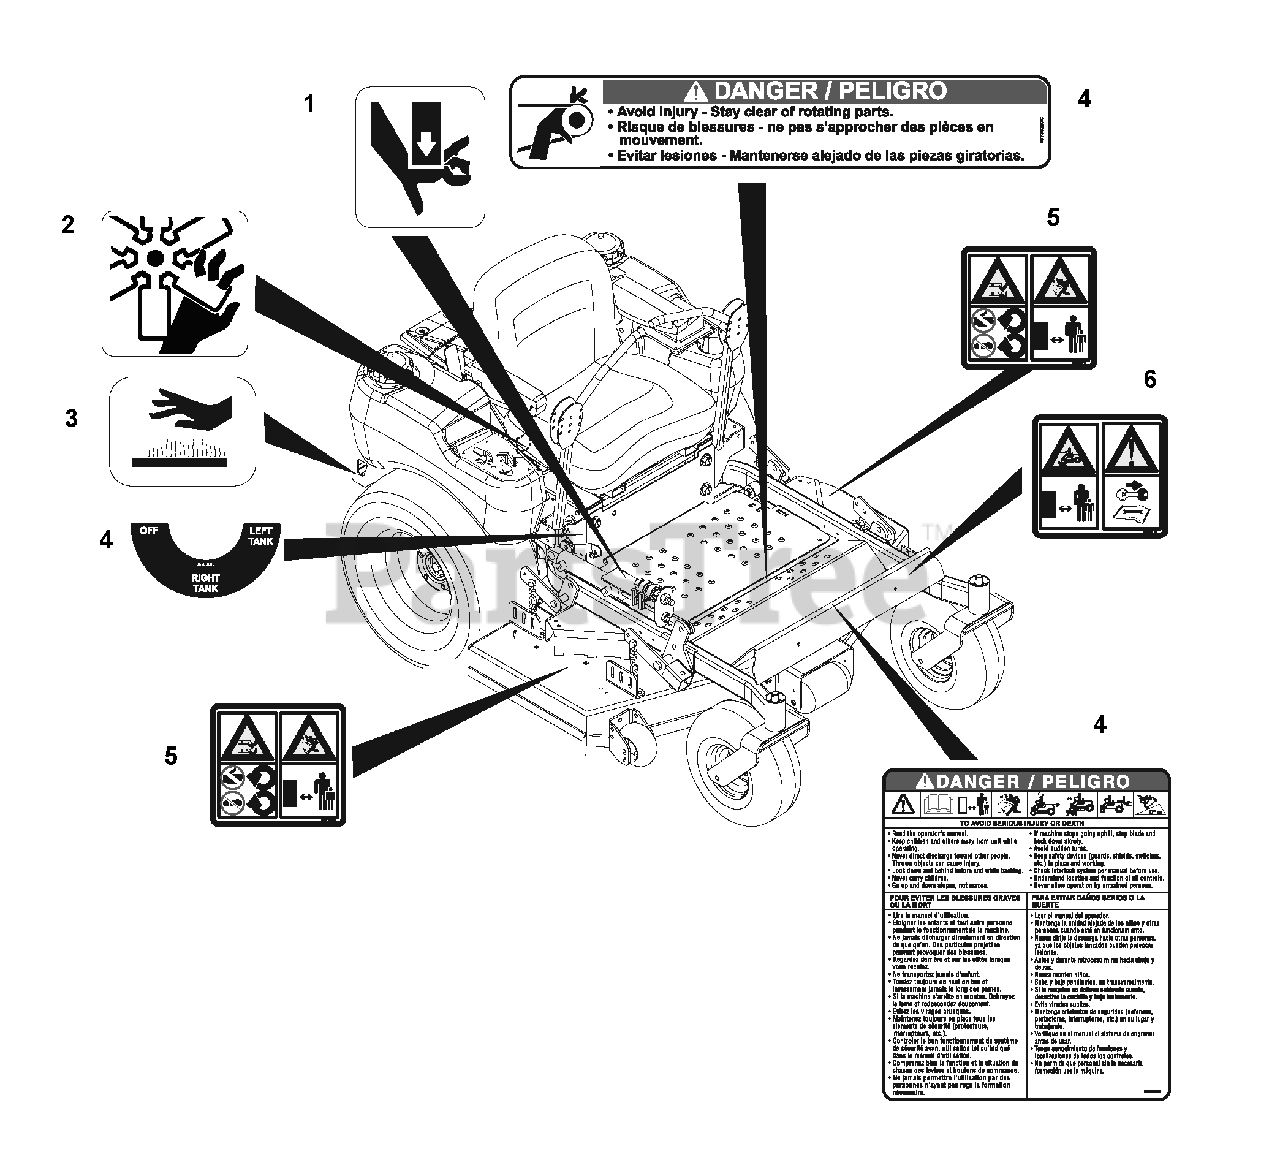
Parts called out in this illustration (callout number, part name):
1	DECAL, PINCH POINT
2	DECAL, DANGER FAN
3	DECAL, HOT SURFACE
4	SET-DECAL, COMMON DANGER/FUEL
5	DECAL, CE DECK
6	DECAL, CE CAUTION
